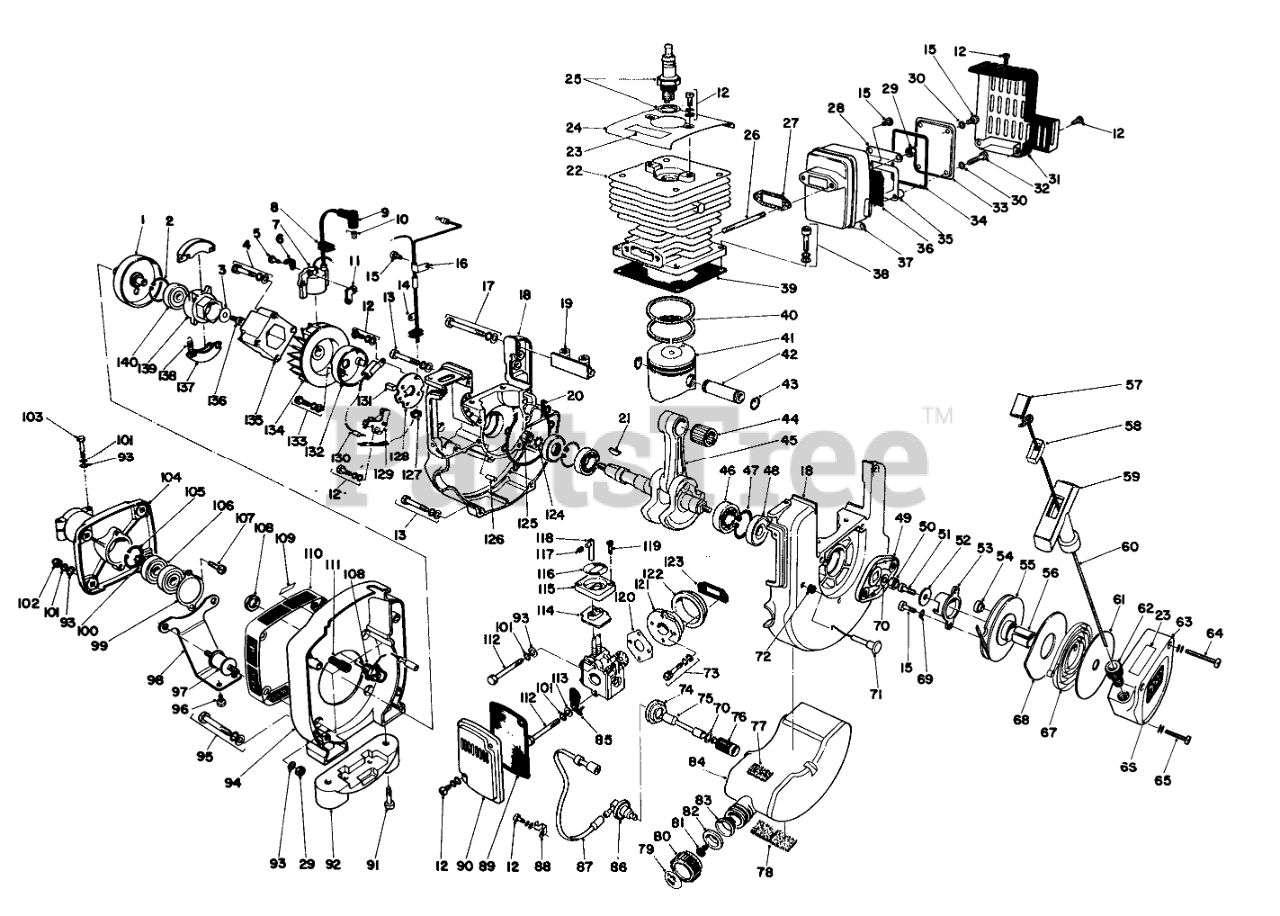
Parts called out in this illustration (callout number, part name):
1	Clutch Drum
2	Circlip
3	Washer
4	Hex Socket Hd. Bolt w/Washer
5	Screw
6	Clamp
7	Ignition Coil
8	Grommet
9	Cap-Spark Plug
10	Coil Spring-Plug Cap
11	Spacer
12	SCREW
13	Hex Socket Hd. Bolt w/Washer
15	Screw
16	Clamp
17	Hex Socket Hd. Bolt w/Washer
18	Crankcase Set
19	Muffler Support
20	Gasket-Crankcase
21	Woodruff Key
22	Cylinder
23	Decal-Hot Surface
24	CYLINDER COVER
25	Spark Plug
26	Stud Bolt
27	Gasket, Muffler
28	Washer
30	Washer
31	Muffler Cover
32	Screw
33	Muffler Lid
34	Gasket-Muffler Lid
35	Screen Holder
36	Screen
37	Muffler
38	Screen, Inlet
39	Gasket, Cylinder Base
40	Piston Ring
41	Piston
42	Piston Pin
43	Circlip, Piston Pin
44	Needle Bearing
45	Crankshaft Assembly
46	Bearing
47	Circlip
48	Oilseal
49	Ratchet Assembly
50	Locknut
51	Lever, Metering
52	Washer
53	Pawl Catcher
55	RECOIL DRUM
56	DRUM BSHG
57	Cap, Starter Handle
58	End Piece
59	Starter Handle
60	Starter Rope
61	Side Plate
62	Rope Guide
63	Starter Case
64	Screw w/Washer
65	SCREW
66	Decal-Toro
67	REWIND SPRING
68	SIDE PLATE (B)
69	Spring Washer
70	Washer
71	Choke Rod
72	Grommet
73	Hex Socket Hd. Bolt w/Washer
75	Fuel Pipe, Inner
76	Fuel Strainer
77	Cushion
78	Cushion
79	Decal Fuel Mix
80	Cap-Fuel Tank
81	Check Valve
82	CHECK VALVE HOLDER
83	Rubber Ring
84	Fuel Tank
85	Choke Shutter
86	Connector
87	Fuel Pipe, Outer
88	Clamp
89	Air Filter
90	Cover, Air Cleaner
91	Screw
92	Cushion
93	WASHER
94	Fan Cover
96	Screw
97	Cushion
98	Bracket
99	Bearing Retainer
100	Circlip
101	Washer
102	Capnut
104	Case, Clutch Drum
105	Circlip
106	Ball Bearing
107	Screw
108	Switch
109	STOP SWITCH DECAL
110	Dust Seal
113	CHOKE SHUTTER SPACER
114	Grommet
115	Frame
116	Decal Guide
117	Knob
118	Adjuster
119	Screw
120	CARB PACKING GASKET
121	Insulator
122	Grommet
123	CARB GASKET
124	Lockwasher
126	Knockpin
128	Stator Plate
129	CONTACT POINT
130	CONDENSER
131	Oil Pad
132	Breaker Cover
133	Screw w/Washer
134	Flywheel
135	Coupler
136	Hex Socket Hd. Bolt
137	Clutch Shoe
138	CLUTCH SPRING
139	Clutch Boss
140	Ball Bearing
